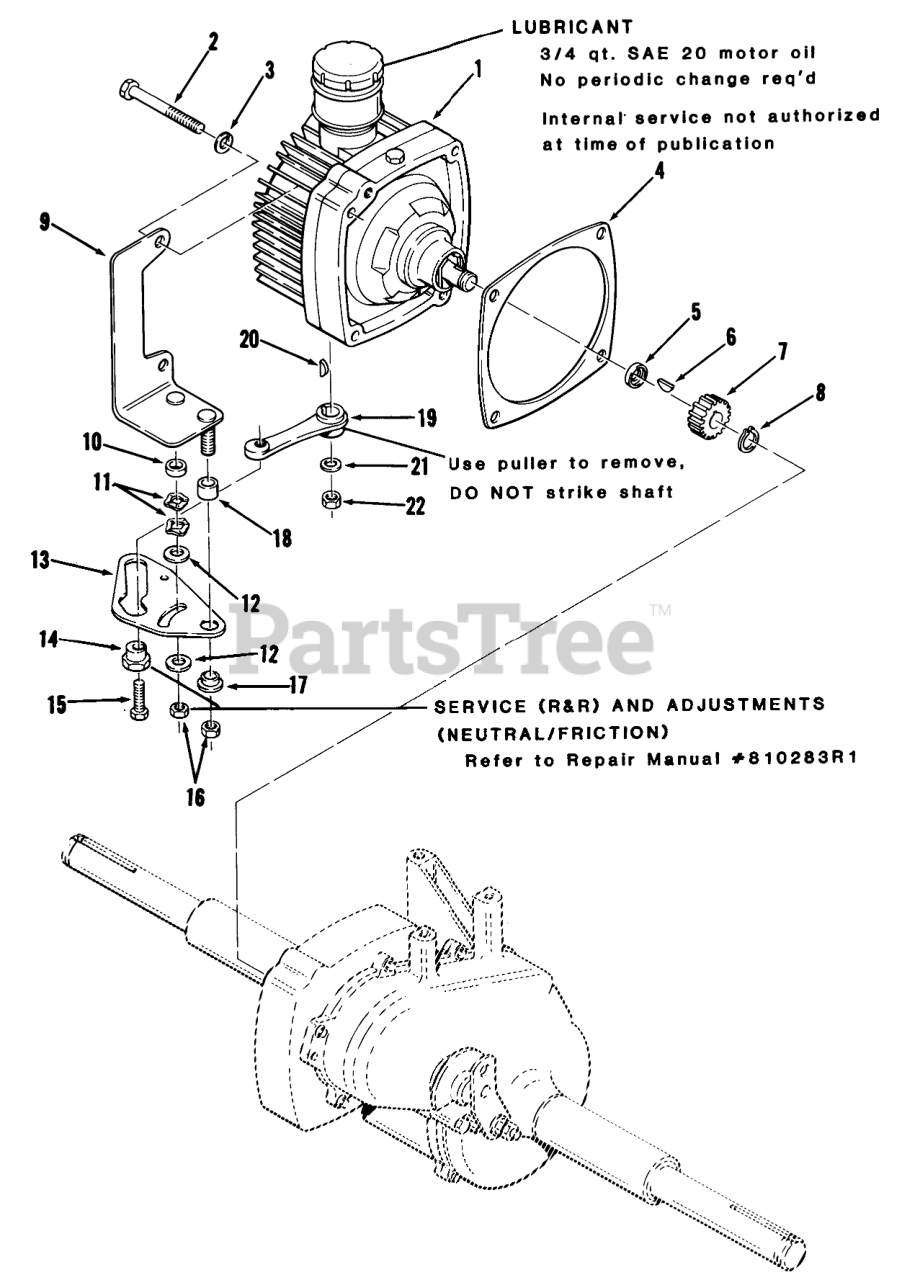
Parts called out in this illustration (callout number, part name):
1	Pump & Motor
2	Screw-Hex. Hd.
3	LOCKWASHER
4	GASKET HYDRO
5	SPACER-GEAR
6	KEY WOODR 1/8X1/2 DI
7	Gear 12 Tooth
8	SNAP RING
9	ASSY CONTROL SUPP R
10	SPACER-FRICTION
11	WASHER-SPRING DISC
12	FRICTION WASHER
13	CAM-SPEED CONTROL (NS)
15	Bolt
17	CAM-SPACER
18	SPACER-PIVOT
19	ARM-SPEED CONTROL
20	KEY WOODR 1/8X1/2 DI
21	Washer
22	Nut
